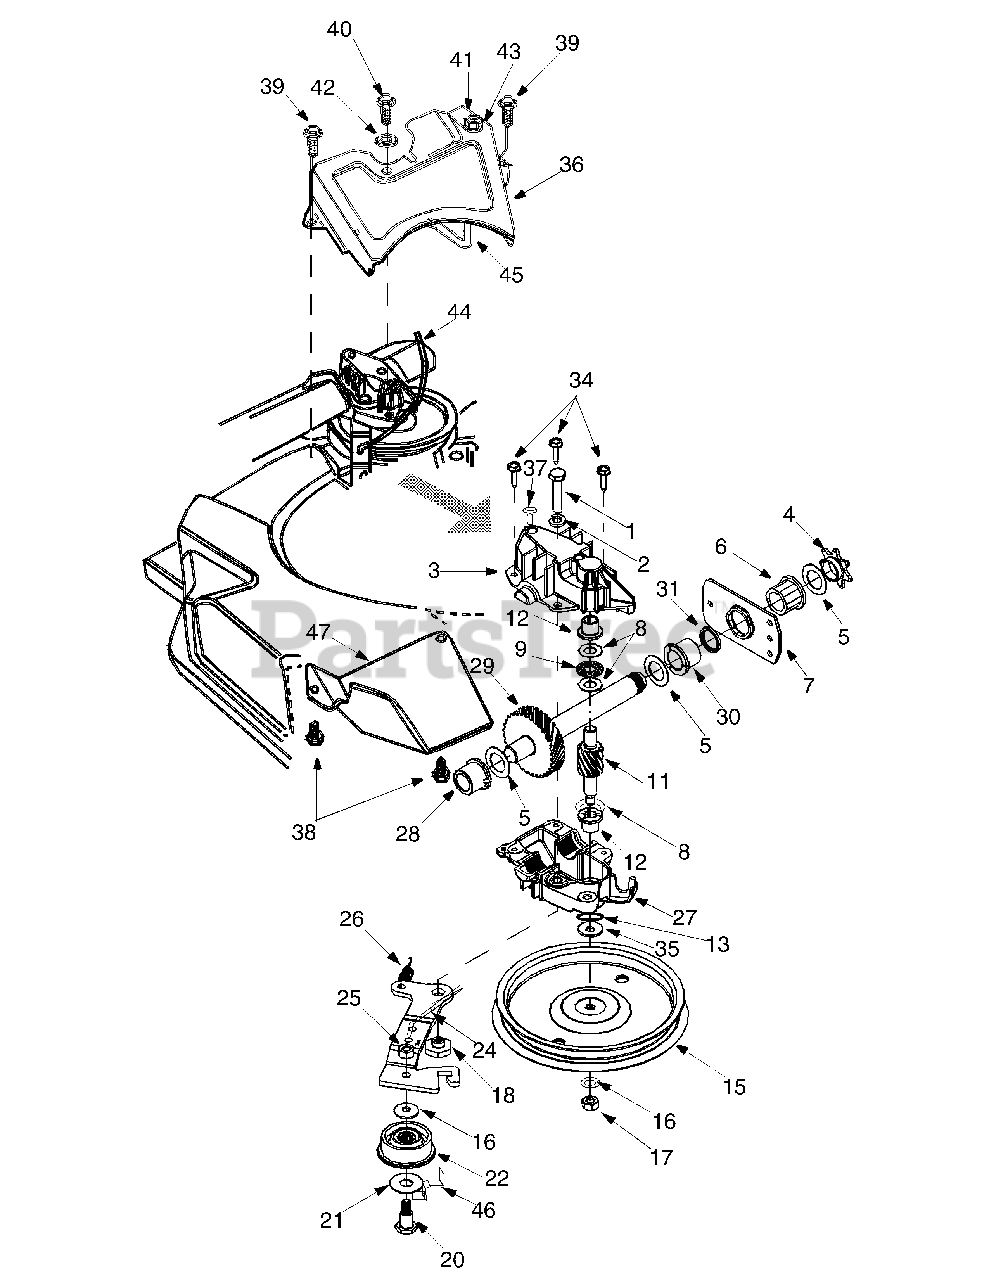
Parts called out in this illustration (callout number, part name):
1	Hex Bolt, 1/4-20 x 1.25''
2	Lock Washer
3	Upper Housing
4	#48 Sprocket 7T
5	Flat Washer 5/8'' ID
6	Hex Flange Bearing
8	Thrust Washer
9	Thrust Bearing
11	11T Helical Gear
12	Flange Bearing
13	Oil Seal
15	Flange Pulley
16	Bell Washer
17	Hex Nut
18	Shoulder Spacer
20	Shoulder Bolt
21	FI-Idler Bracket Assembly
22	Needle Bearing
24	Idler Bracket Assembly
25	Hex Patch Lock Nut
26	Extension Spring
27	Lower Housing
28	Flange Bearing 0.56'' Dia
29	Shaft Assembly
30	Flange Bearing
31	Oil Seal
34	AB Screw #10-16
35	Hex Washer
38	Hex B-Tap Screw
39	Hex AB Tap Screw
40	Hex B-Tap Screw
41	Hex Nut
42	Bell Washer
43	Lock Washer
44	Self-Propelled Cable
45	Self-Propelled Belt Guard
46	Belt Guard
